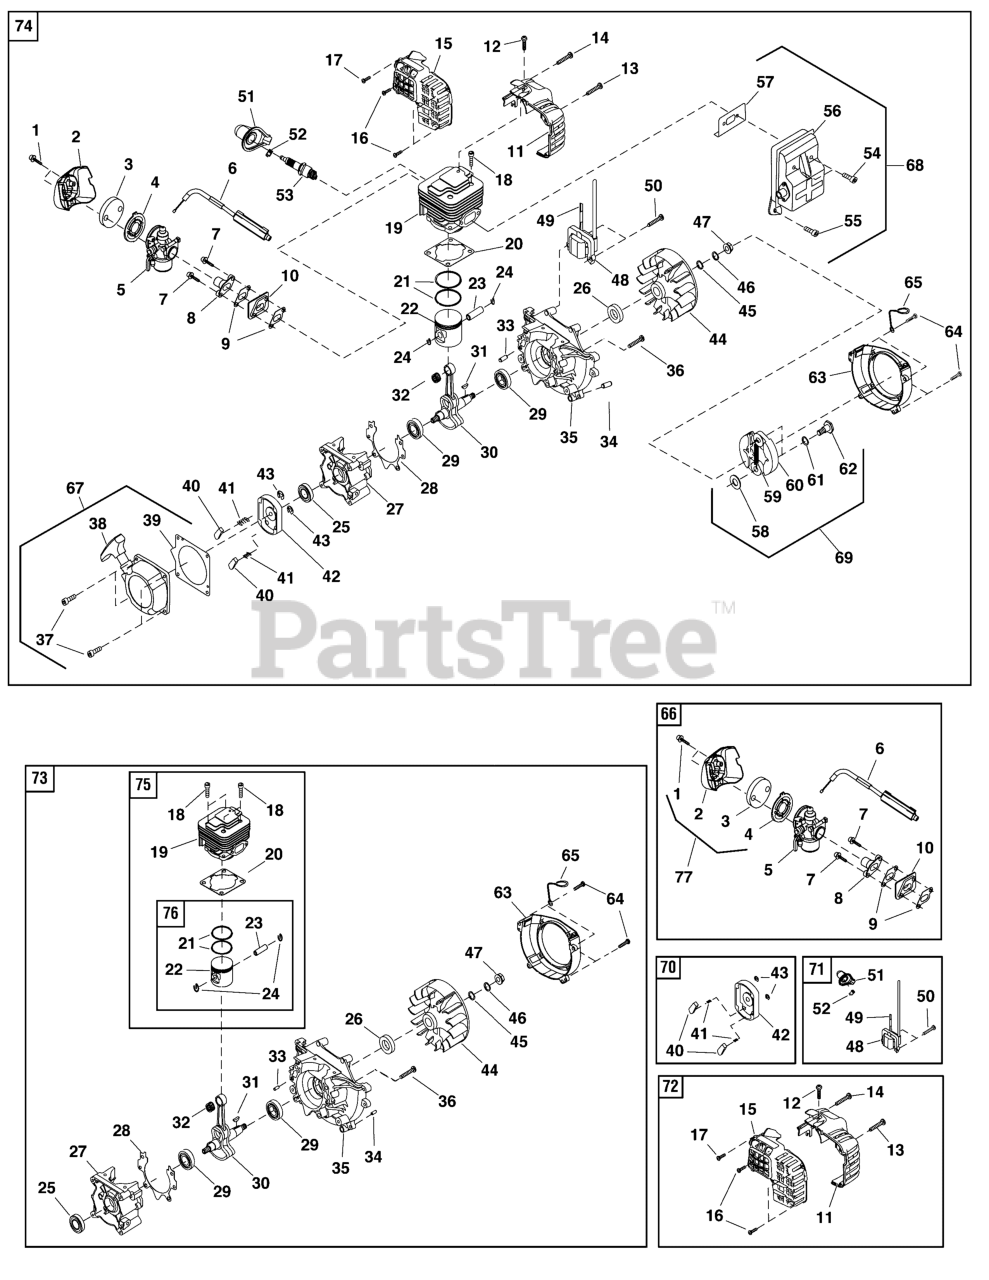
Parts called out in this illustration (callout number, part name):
1	BOLT, M4 x 25
2	COVER, Cleaner, Outer
3	FILTER
4	BRACKET, Filter Net
5	CARBURETOR, Ruixing
6	FUEL CABLE ASSEMBLY
7	BOLT, M5 x 25
8	ADMITTING PIPE
9	GASKET, Admitting Pipe
10	GASKET
11	SHROUD, Front
15	SHROUD, Rear
16	SCREW, Self Tapping, 5 x 20
17	SCREW, Self Tapping, ST4.2 x 25
18	BOLT, M5 x 20
19	CYLINDER
20	GASKET, Cylinder
21	RING, Piston
22	PISTON
23	PIN, Piston
24	RING, Pin Retain
25	SEAL, Oil, 11.7 x 22 x 7
26	OIL SEAL, 30 x 14.7 x 7
27	CRANK CASE, Rear
28	GASKET, Crank Case
29	BEARING, 6201/P6
30	CRANKSHAFT
31	KEY, 3 x 5 x 13
32	BEARING, Needle
33	PIN, Cylindrical, B5 x 12
34	PIN, Cylindrical, B4 x 10
35	CRANK CASE, Front
38	STARTER
39	STARTER PAD
40	STARTER CINCH
41	SPRING, Starter
42	STARTER BOX
43	RING, Retainer
44	FLY WHEEL
45	WASHER, Flat, Dia. 8
46	WASHER, Spring, Dia. 8
47	NUT, M8
48	MAGNETO COIL
49	CORD, Magneto
51	BOOT, Spark Plug
52	CLIP, Spark Plug
53	SPARK PLUG
54	BOLT, M5 x 55-10.9
56	MUFFLER
57	GASKET, Muffler
58	WASHER, B
59	SPRING, Clutch
60	EXPANDER, Complete
61	WASHER, Wave
62	SCREW, Shaft
63	COVER, Fan
65	BRACKET
66	KIT, Air Cleaner & Carburetor
67	KIT, Starter Assembly
68	KIT, Muffler Assembly
69	KIT, Expander Assembly
70	KIT, Start Reel Assembly
71	KIT, Magneto Assembly
72	KIT, Shroud Assembly
73	KIT, Cylinder Assembly
74	ENGINE ASSEMBLY, Complete
75	KIT, Cylinder Head
76	KIT, Piston
77	KIT, Air Cleaner
